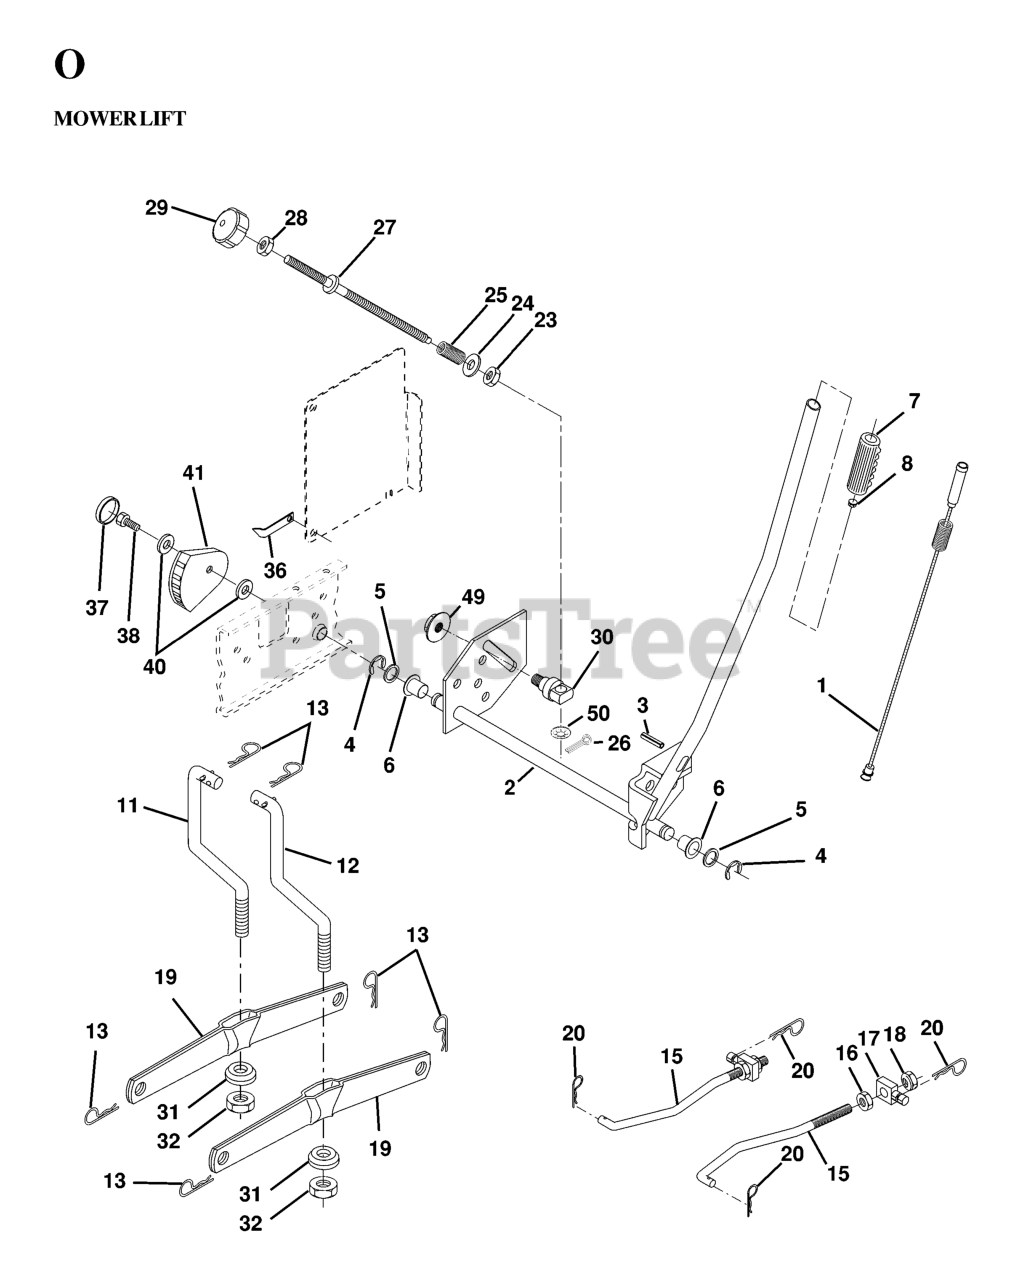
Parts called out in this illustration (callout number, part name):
1	WIRE.INNER.HANDLE.LIFT.LEVER
2	SHAFT ARM LIFT RH
3	PIN GROOVE.
4	RETAINING RING LT
6	BEARING.NYLON
7	GRIP HANDLE
8	PLUNGER BUT KIT
10	SPRING, COMP T
11	LINK LIFT LH
12	LINK LIFT RH
13	RETAINER-SPRNG RB
15	FRONT LINK
16	NUT.HEX.JAM.1/2-13
17	TRUNION
18	NUT.LK.W/WSH.1/2.
19	ARM.REAR.SUSPENSION
20	SPRING RETAINER
25	SPRING**
26	COTTER PIN
27	ROD ADJ LIFT
28	NUT
29	KNOB INF 3/8-16
31	NUT CROWNLOCK 3/8-24
32	BEARING PIVOT
36	POINTER, HEIGHT INDICATOR(2 2)
38	SCREW.THDROL.5/16-18X3/4.TTY
41	IND. HEIGHT STLT
49	NUT
